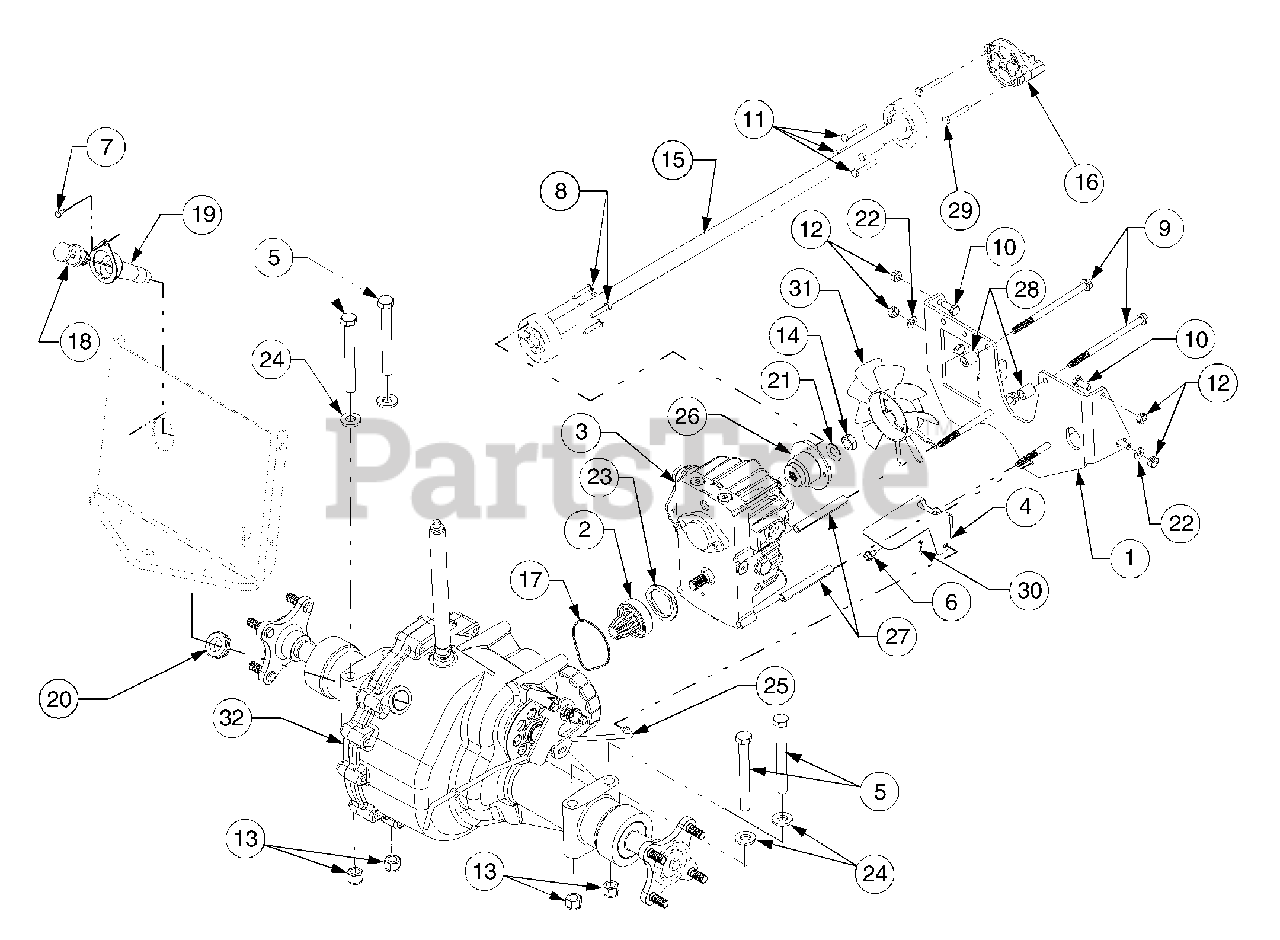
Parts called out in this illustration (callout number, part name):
1	Bracket, Torque
2	Gear Assembly, Pinion
3	Transmission, Hydrostatic
5	Screw, Hex Cap, 1/2-20 x 4.5 GR5
6	Scrw, Hx Wsh Hd Tapp, 1/4-20 x 5
7	Scrw, Hx Wsh Hd Tapp, 10-16 x .44
8	Screw, Hex Patch, 1/4-20 x 1.25 GR5
9	Scrw, Hx Hd Tapp, 5/16-18 x 5.25
10	Screw, Hex Cap, 5/16-18 x .75 GR5
11	Screw, Hex Patch, 1/4-20 x 1.62 GR5
12	Nut, Hex Cntr Lock, 3/8-16
13	Nut, Hex Nylon Lock, 1/2-20 GR2
14	Nut, Hex Top Lock Jam, 1/2-20
15	Shaft, Drive, 30.875 Lg
16	Adapter, Engine
17	Seal, Gland
18	Dipstick, Transmission
19	Holder, Dipstick
20	Grommet, Rubber, .75 x 1.063
21	Washer, Belleville
22	Washer, Flat, .344 x .688 x .065
23	Washer, Spring
24	Washer, Flat, .531 x 1.062 x .134
25	Rod, Hydro Dump Valve
26	Adapter, Hydro Pump
27	Spacer, Hydro, .323 x .443 3.51
28	Spacer, Hydro, .323 x .600 x .74
29	Screw, Hex Patch, M10-1.50 x 90mm
30	Internal Cotter Pin
31	Fan, Pump
32	See "Hydro Transmission" for Parts Info.
